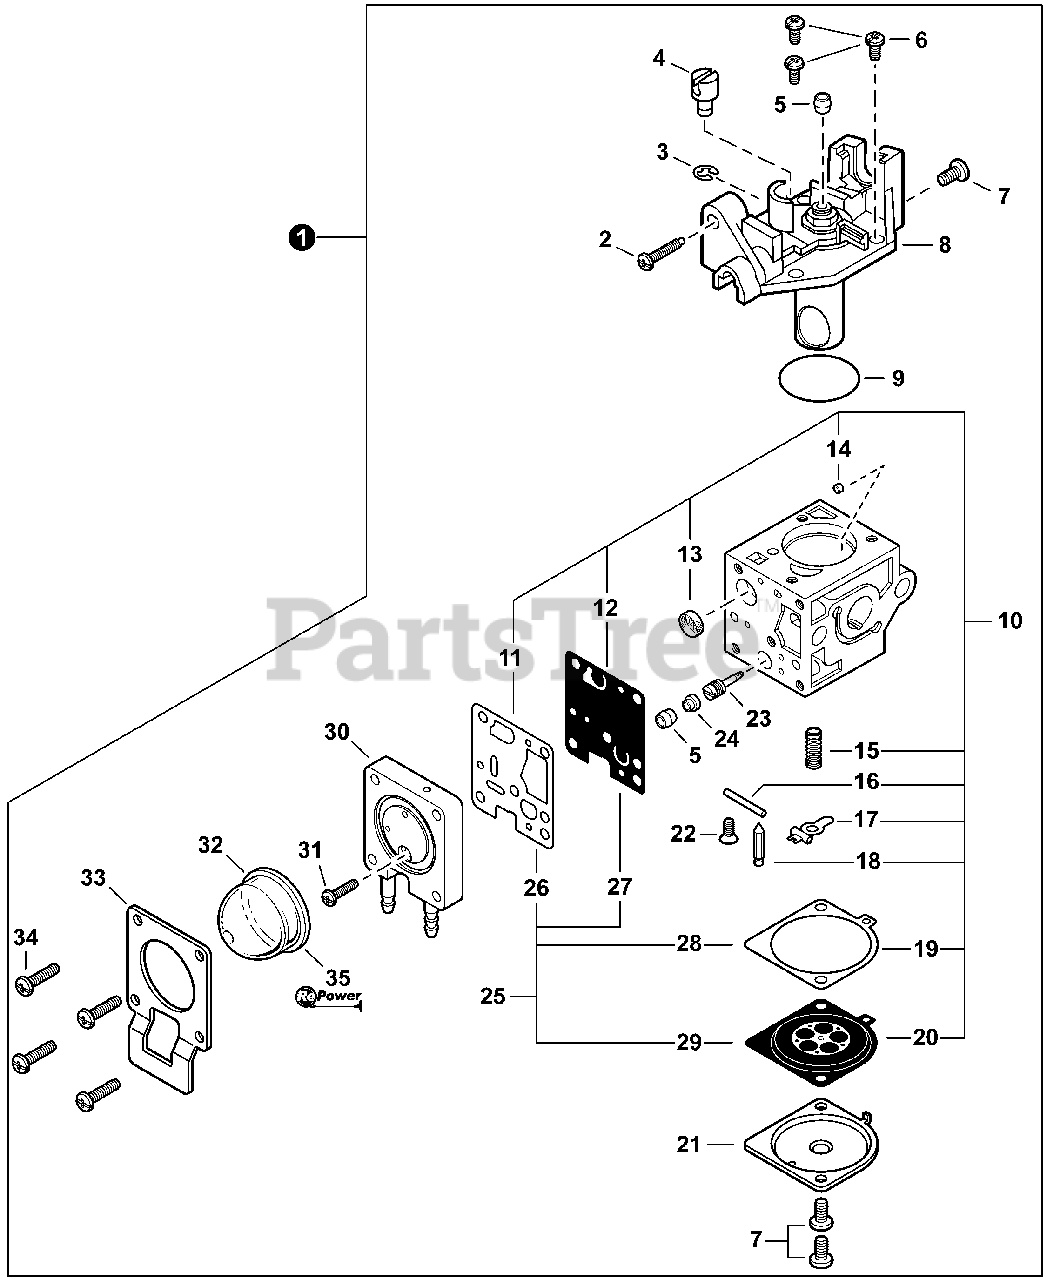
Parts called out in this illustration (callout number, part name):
1	CARBURETOR - RB-K93
2	SCREW, IDLE ADJUST
8	COVER ASSY, ROTOR
9	O-RING
10	REPAIR KIT, CARBURETOR
11	GASKET, PUMP
12	DIAPHRAGM, PUMP
13	SCREEN, FUEL INLET
14	GUIDE, ROLLER
15	SPRING, METERING LEVER
16	PIN, METERING LEVER
17	LEVER, METERING
18	VALVE, INLET NEEDLE
19	GASKET, METERING DIAPHRAGM
20	DIAPHRAGM, METERING
21	COVER, METERING DIAPHRAGM
23	NEEDLE, HIGH SPEED
24	CAP, LIMITER
25	GASKET / DIAPHRAGM KIT
26	GASKET, PUMP
27	DIAPHRAGM, PUMP
28	GASKET, METERING DIAPHRAGM
29	DIAPHRAGM, METERING
30	BODY ASSY, PURGE
32	BULB, PURGE
33	RETAINER, PURGE BULB
35	FUEL SYSTEM KIT
